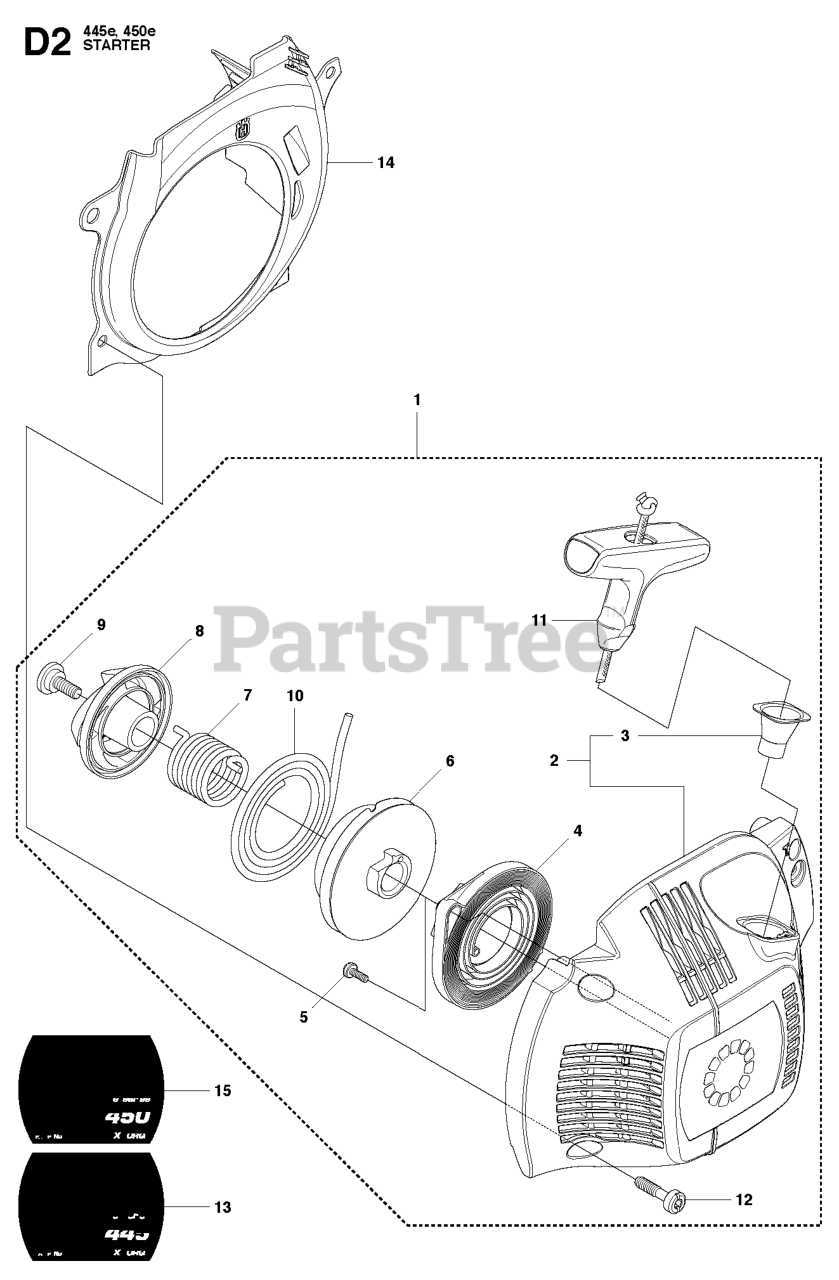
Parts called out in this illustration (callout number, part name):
1	FUEL TANK ASSY NBR+PVC
1	FUEL TANK ASSY
1	STARTER ASSY
2	PIPE
2	STARTER HOUSING
4	RP FUEL FILTER
4	SPRING CASSETTE ASSY
5	TANK CAP COMP
6	SKID PLATE
6	STARTER PULLEY
7	BOLT
10	STARTER ROPE
13	LABEL
14	COOLING AIR CONDUCTOR
15	LABEL
